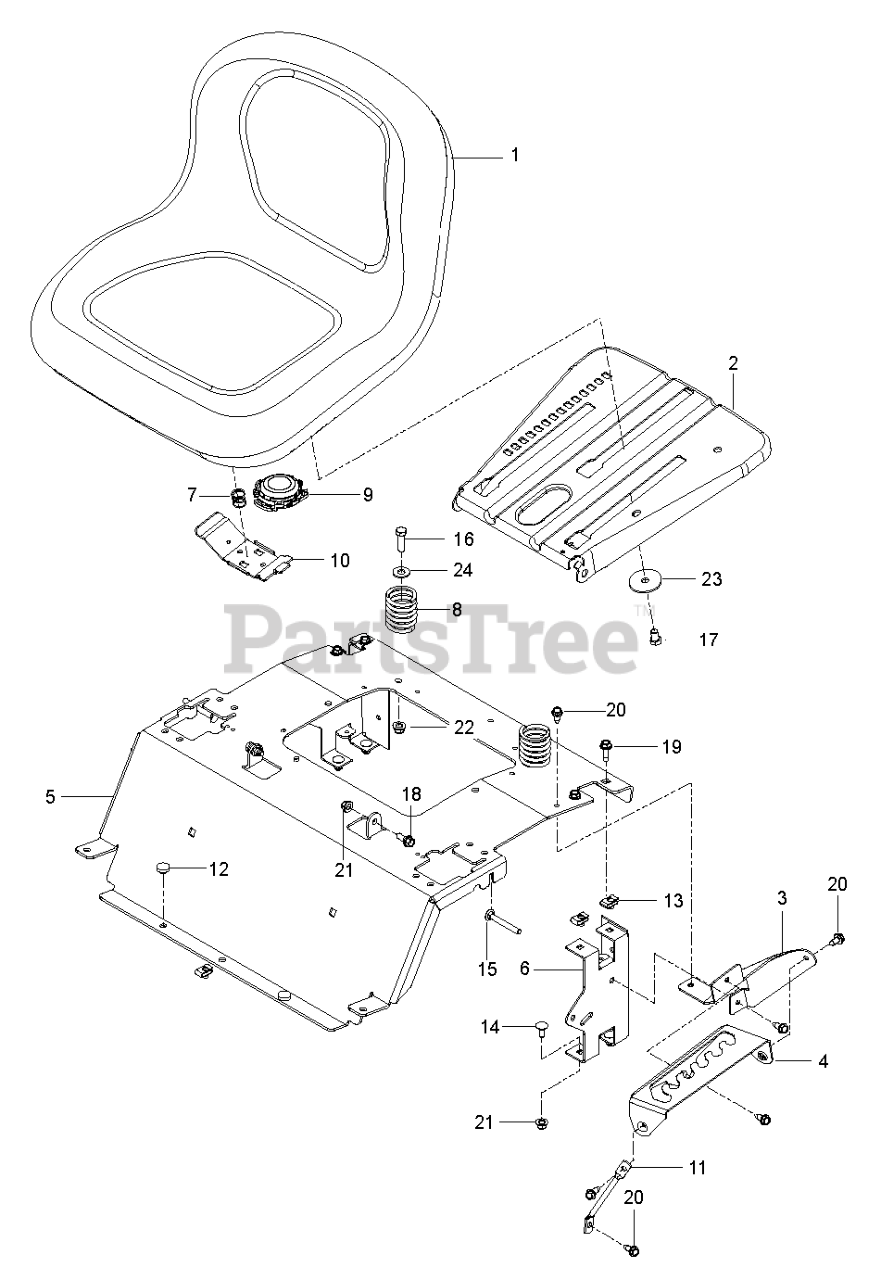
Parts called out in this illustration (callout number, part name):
1	SEAT.TH150.MS498.GRY.HUSQ.TEX
2	PLATE.PNT.SEAT.SLIDE.3PT.EDIP
3	PLATE.SUPPORT.DECK.LIFT.X431
4	PLATE.DECK.LIFT.X431
5	SUPPORT SEAT ORANGE
6	SUPPORT REAR SEAT BLACK
7	SPRING.LATCH.SEAT.TEX
8	SPRING.COMPRESSION.SEAT.BLACK
9	SWITCH.SEAT.DELTA.OPC.
10	HANDLE.SLIDE.SEAT.TEX.BLACK
11	SUPPORT.LEG.DECK.LIFT
12	GROMMET.BUMPER
13	U-CLIP 5/16-18 NUT RETAINER
14	RP BOLT 5/16-18 X3/4 ZN/YEL GR
15	RHSNB 5/16-18 X 2-1/2 GR5 ZD
16	BOLT
17	HCS 3/8-16 X 5/8 GR 5 ZD
18	BOLT, SHOULDER
19	SCREW.THDROL.5/16-18X3/4.TTY
20	BOLT.5/16HEX.WHS.HD
21	5/16-18 NYLOC FLANGE NUT
22	NUT 3/8-16 HEX FLG NYLOC ZD
23	WASHER, 3/8 SPEC
24	WASHER.WINGED.3/8ID.1.5OD
